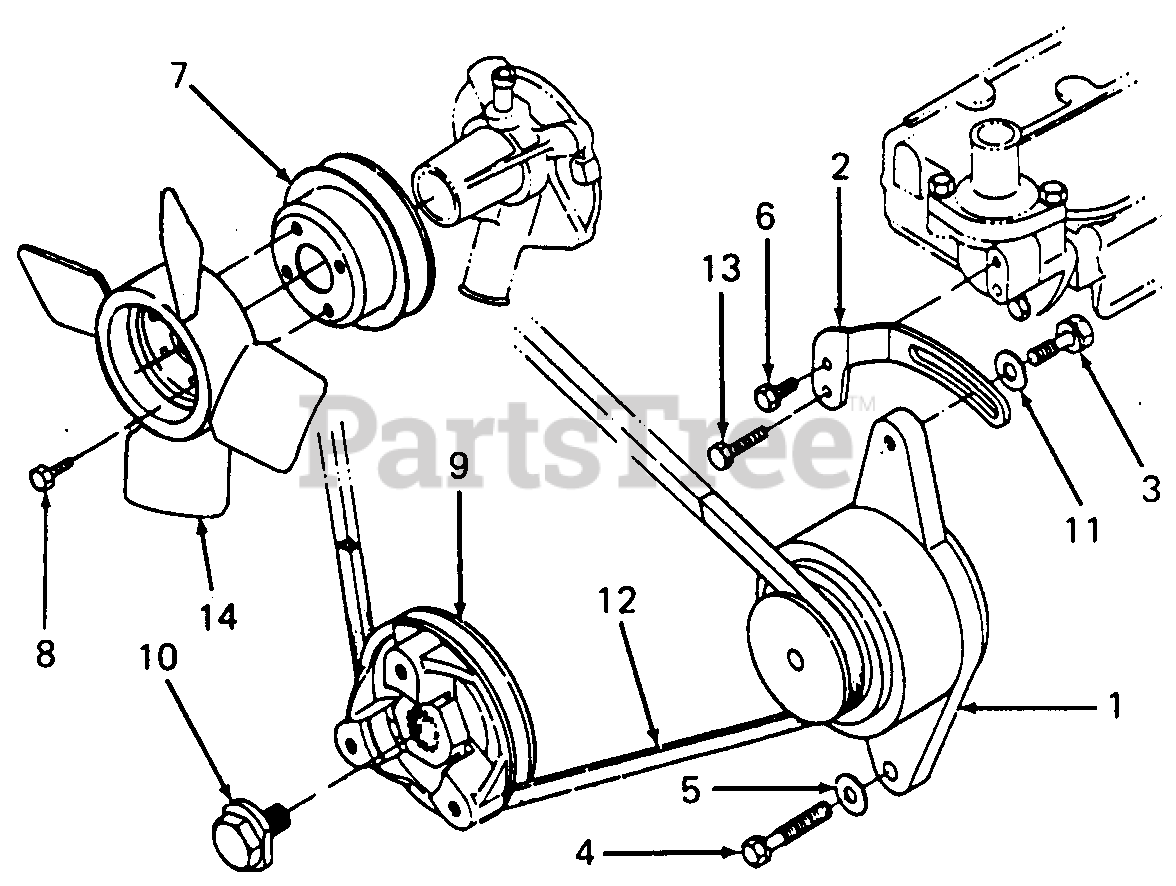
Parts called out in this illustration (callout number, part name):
1	Alternator
2	Support, Alternator
3	Screw w/Washer
4	Screw w/Washer
6	Screw w/Washer
7	Pulley, Water Pump
8	Screw, Hex Washer Head
9	Pulley, Alternator Drive
13	Screw w/Washer
